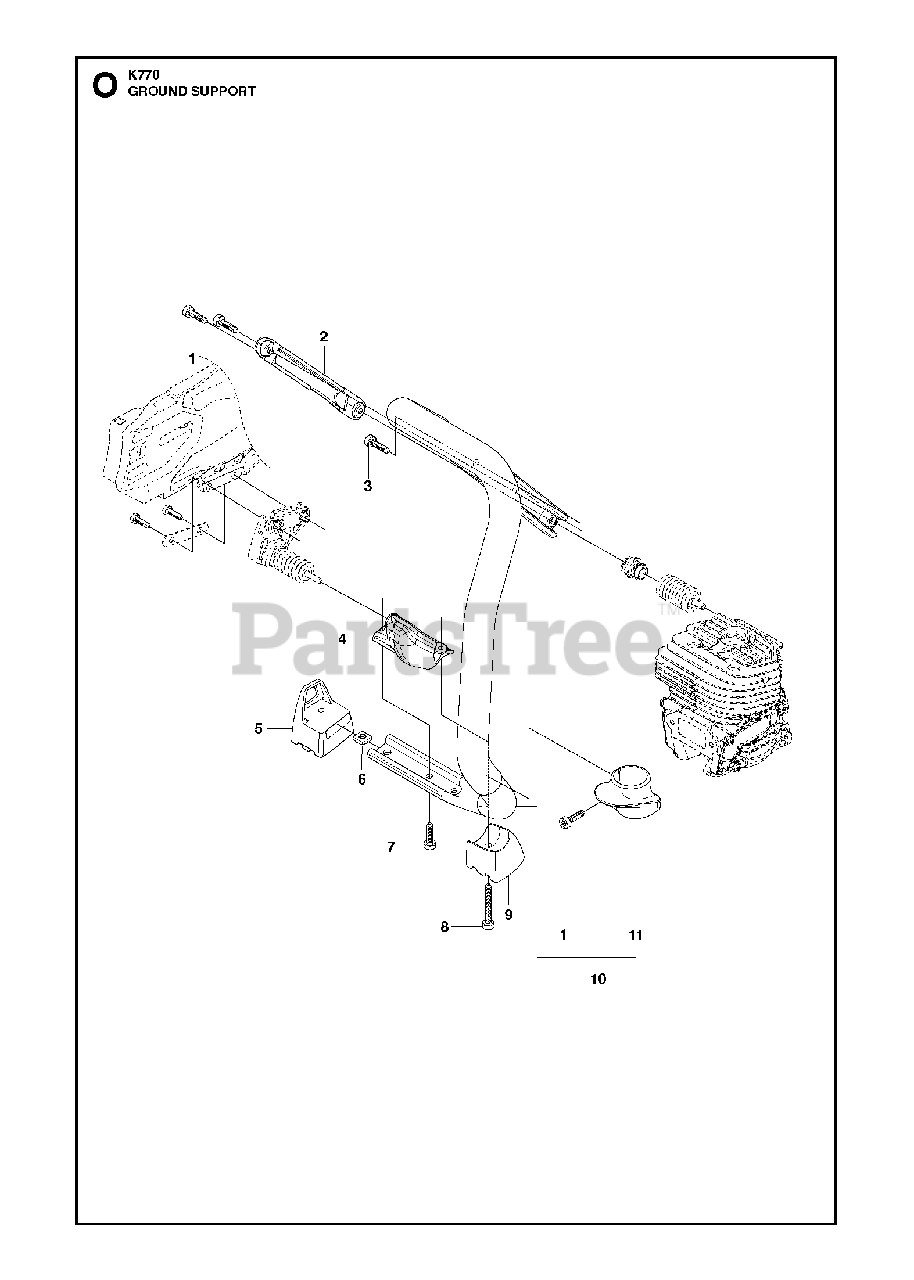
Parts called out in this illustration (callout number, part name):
1	SCREW ITXSCT
3	SCREW ITXSCM
4	SPRING RETAINER
5	GROUND SUPPORT
7	SCREW ITXSCM
8	SCREW ITXSCM
9	GROUND SUPPORT
10	HANDLE ASSYIncl. 1,11
